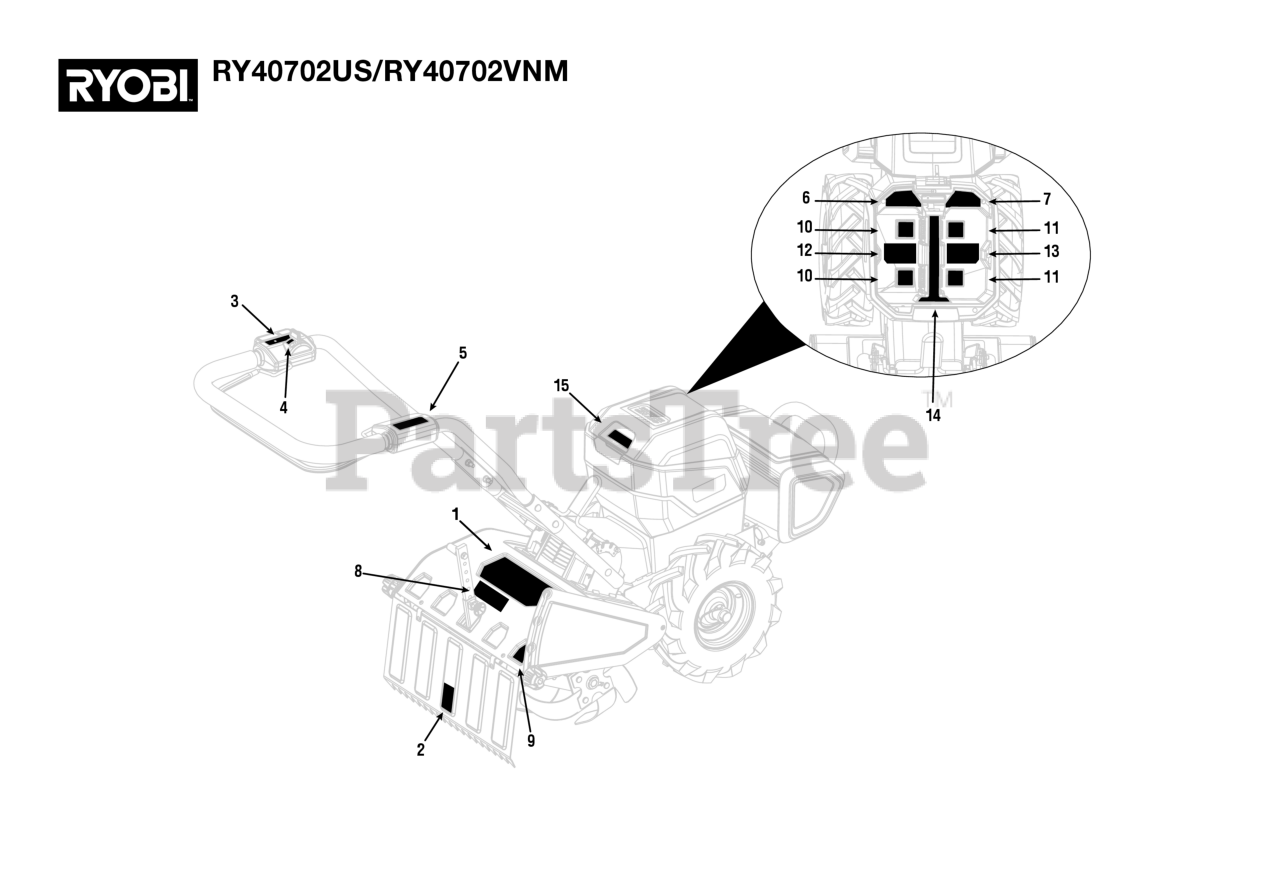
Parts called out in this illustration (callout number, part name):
1	Data/Icon/Warning Label
2	Cut Foot/Hands Label
3	LED Label
4	Speed Label
5	Starting Instructions Label
6	Pair A Top Label
7	Pair B Top Label
8	Depth Stake Label
9	Side Panel Instruction Label
12	A Min Battery Label
13	B Min Battery Label
14	Center Label
15	18in Tilling Width Label
